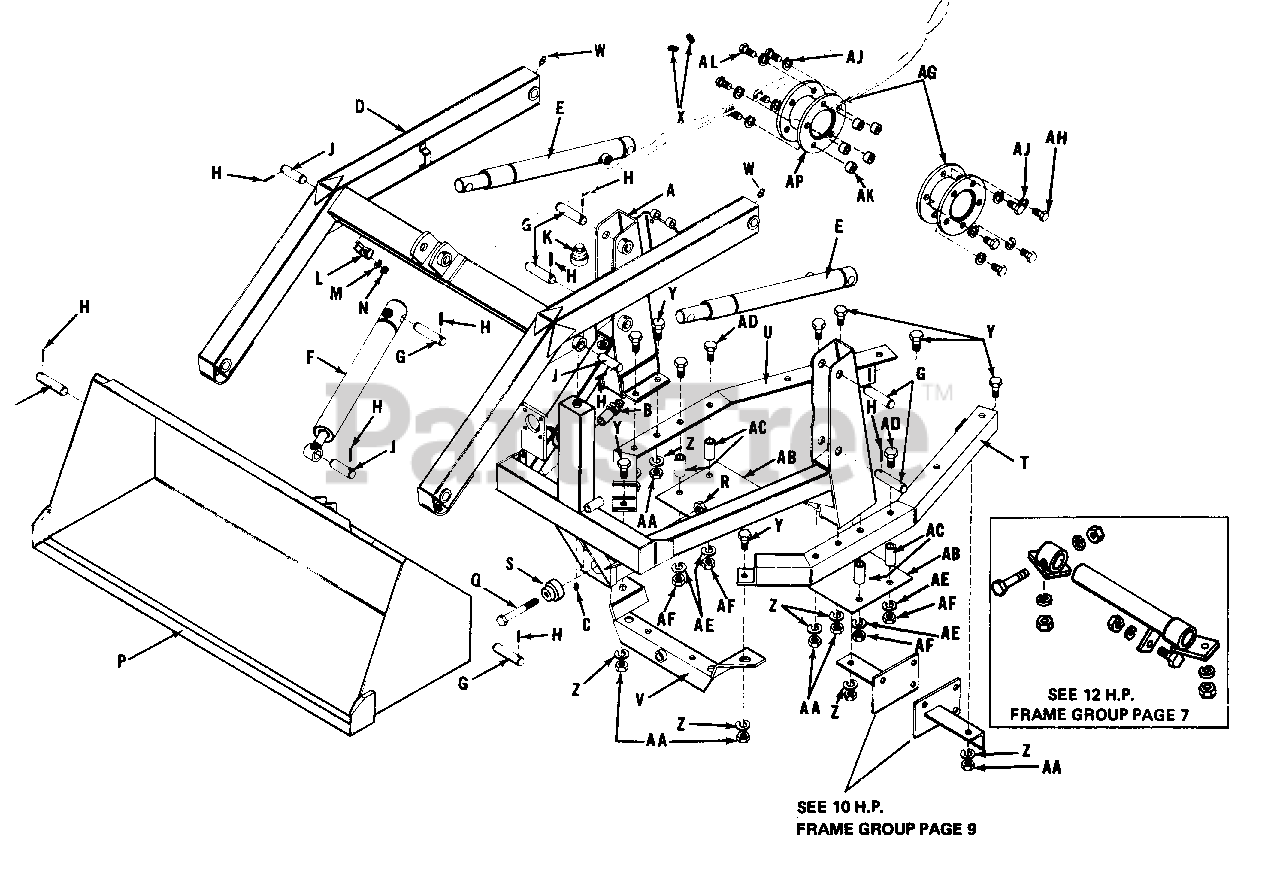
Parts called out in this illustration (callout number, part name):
A	Main Frame Ass'y.
C	Pipe Plug, 1/4" N.P.T.
D	Lift Arm Assembly
E	Lift Arm Cylinder
F	Bucket Cylinder
G	Loader Pin
H	Roll Pin, 3/16" x 1-1/4"
J	Lift Arm Pin
L	Hose Clamp
M	Lock Washer, 1/4"
N	Hex. Full Nut, 1/4"-20 N.C.
P	Bucket, 42"
Q	Hex. Capscrew, 1/2"-20 N.F. x 4-1/4"
R	Full Hex. Lock Nut, 1/2"-20 N.F.
S	Front Mount
T	Left Sub-Frame
U	Right Sub-Frame
V	Front Mount Bracket
W	Grease Fitting
X	Cup Pt. Setscrew, 7/16"-20 N.F. x 1/2"
Y	Hex. Capscrew, 1/2"-13 N.C. x 1-1/4"
Z	Lock Washer, 1/2"
AA	Full Hex. Nut, 1/2"-13 N.C.
AB	Floor Board
AD	Hex. Capscrew, 1/2-13 N.C. x 2-3/4"
AE	Lock Washer, 1/2"
AF	Full Hex. Nut, 1/2"-13 N.C.
AG	Dual Wheel Adapter Ass'y.
AH	Hex. Capscrew, 7/16"-20 N.F. x 1"
AJ	Lock Washer, 7/16"
AL	Hex. Capscrew, 7/16"-20 N.F. x 1-1/2"
